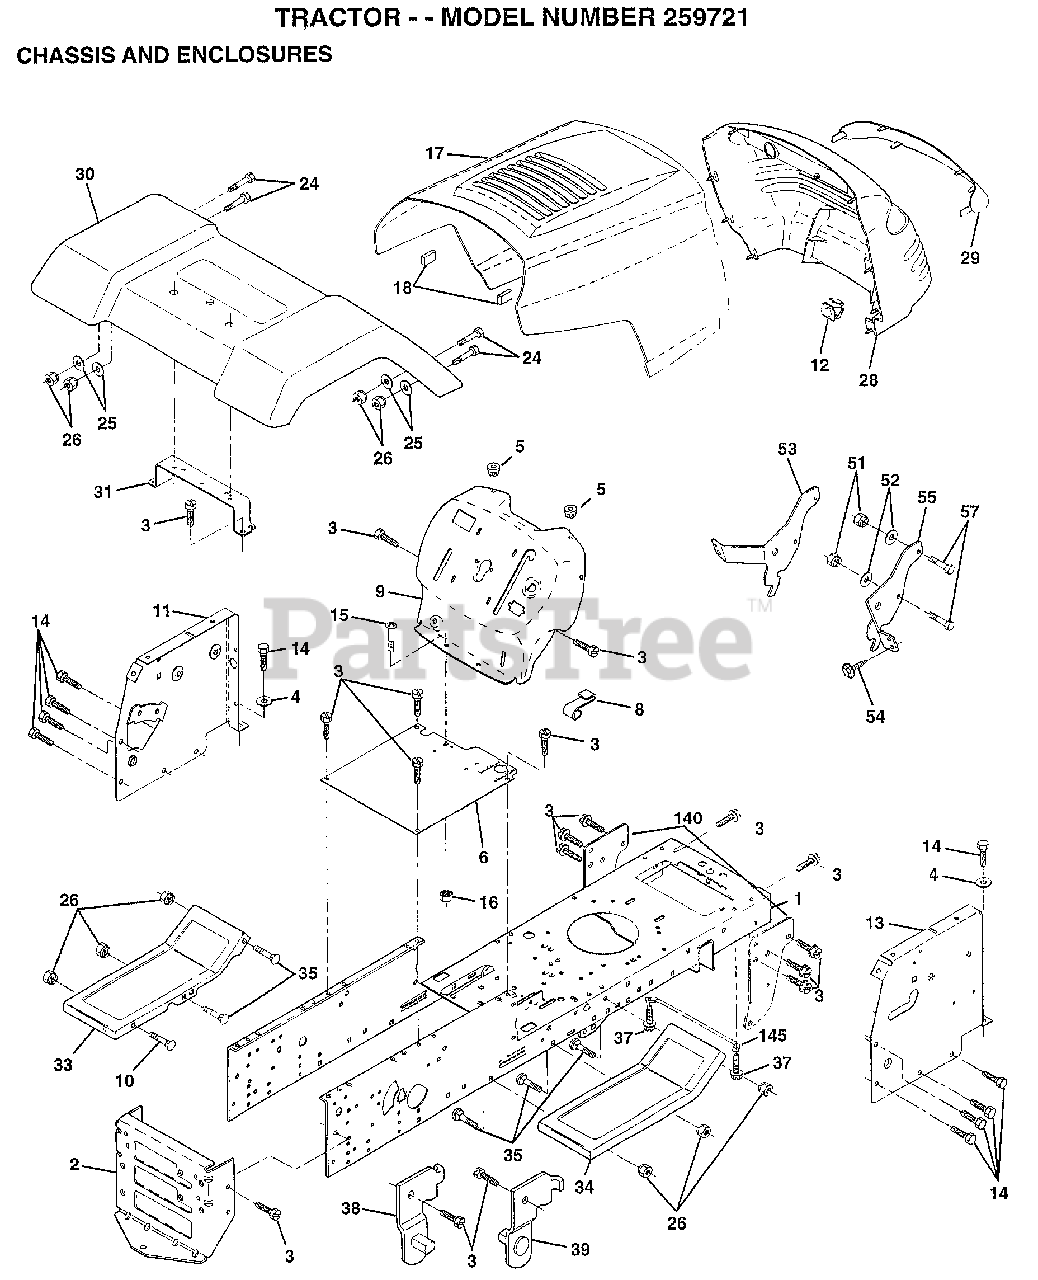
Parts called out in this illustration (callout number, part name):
1	CHASSIS.STAMPING
3	SCREW
4	WASHER
5	BUMPER-HOOD/DASH
6	SADDLE-SILKSCREEN
8	CLIP.RETAINER
9	DASH SILKSCREEN
11	"PANEL-DASH,LH"
12	CLIP.TINNERMAN
14	SCREW LT
15	SCREW
17	HOOD.STEEL.ASSY
24	BOLT
25	WASHER
26	NUT
28	GRILLE-MS428
29	LENS.GRILLE.PRIVATE LABEL
30	FENDER.PNTL.LT.W/O.SHIFT
31	BRKT FENDER
33	FOOTREST.LH.PERF.
34	FOOTREST.RH.PERF.
35	BOLT
37	SCREW LT
38	BRACKET ASM LH
39	BRACKET ASM RH
51	NUT
52	WASHER
53	BRACKET.GRILLE.LH
54	SCREW.HEX.WS.HD
55	BRACKET.GRILLE.RH
140	BRKT SUSPENSION
145	"ROD POVOT,CHASSIS"
